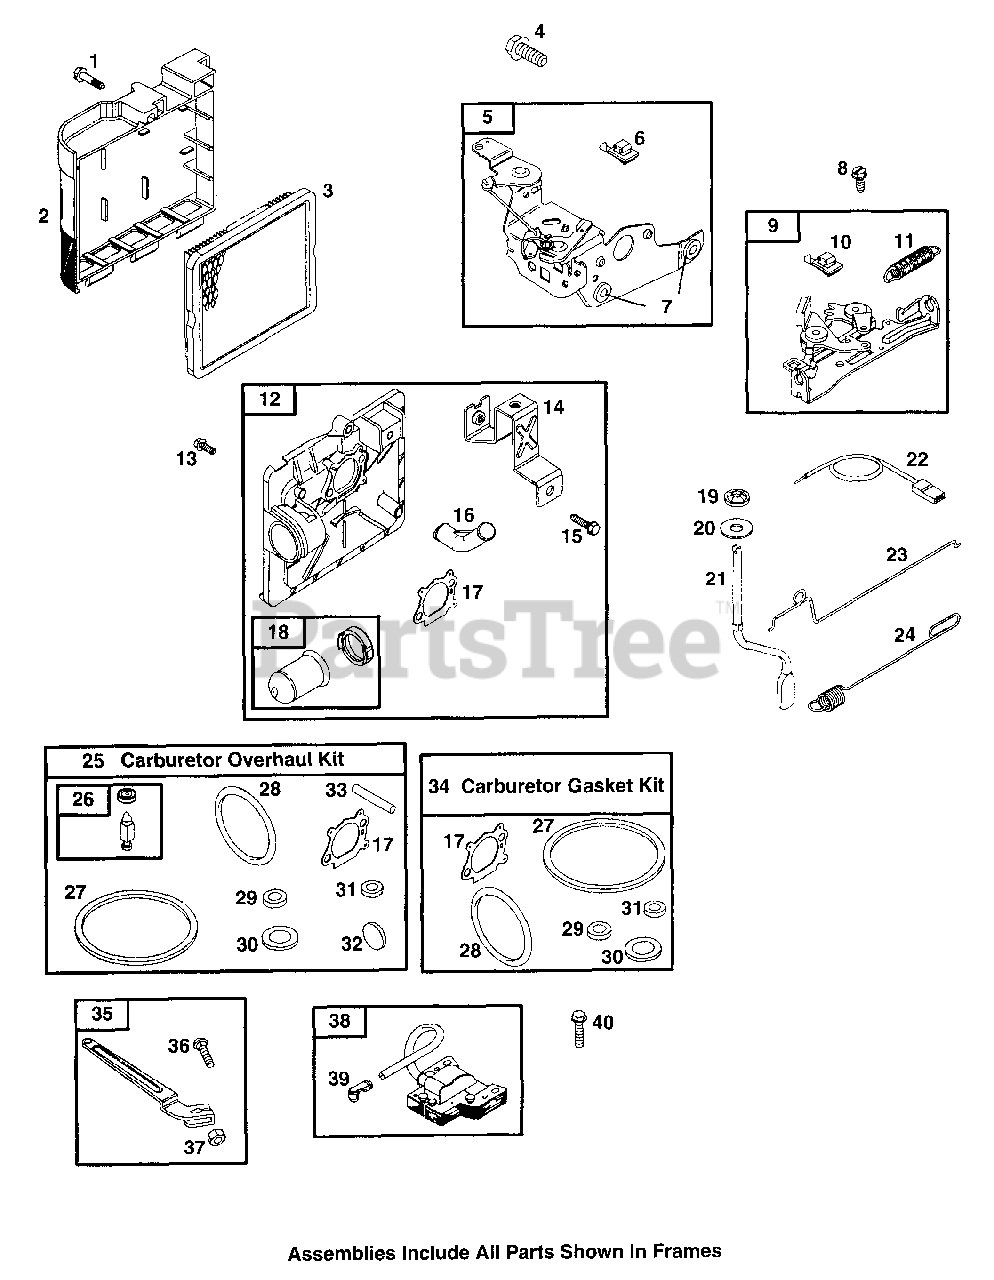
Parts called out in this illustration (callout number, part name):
1	Screw (Air Cleaner Cover)
2	Air Cleaner Cover
3	A/C Cartridge Filter
4	Screw (Control Bracket)
5	Control Bracket
6	Stop Switch
7	Spacer
8	Screw (Brake)
9	Brake
10	Stop Switch
11	Brake Spring
12	A/C Primer Base
13	Screw (A/C Primer Base)
14	Air Cleaner Primer Bracket
15	Screw (Support Bracket)
17	Air Cleaner Gasket
18	Carburetor Primer
19	Retainer Governor Shaft
20	Washer (Governor Crank)
21	Governor Crank
23	Mechanical Governor Link
24	Governor Spring
25	Carburetor Overhaul Kit
26	Needle/Seat Kit
27	Float Bowl Gasket
28	O-Ring Seal (Intake Manifold)
29	Choke/Throttle Dust Seal
30	Sealing Washer
31	Throttle Shaft Seal
32	Welch Plug
33	Float Hinge Pin
34	Carburetor Gasket Set
35	Governor Control Lever
36	Bolt (Governor Control Lever)
37	Nut (Governor Control Lever)
38	Magneto Armature
39	Sparkplug Terminal
40	Screw (Magneto Armature)
